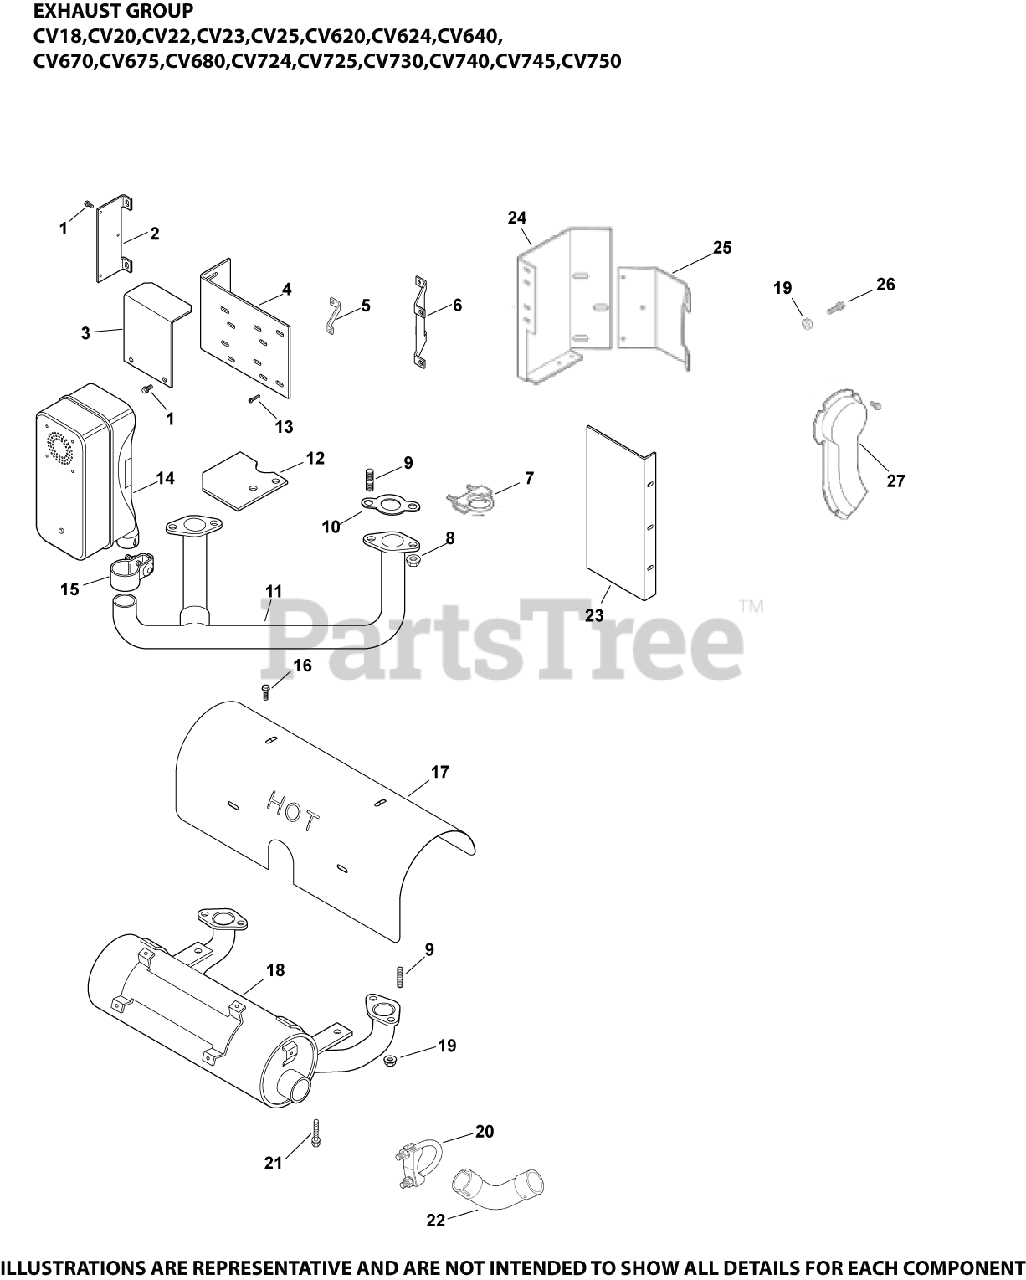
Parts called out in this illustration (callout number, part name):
8	NUT, FLG M8X1.25
9	STUD, M6X1.0X36
10	GASKET, EXHAUST
16	SCREW, SEMS DRILL #8-18X1/2"
17	DUCT, HEAT SHIELD
18	MUFFLER USE 24 068 116-S
28	NUT, FLG M6X1.0
